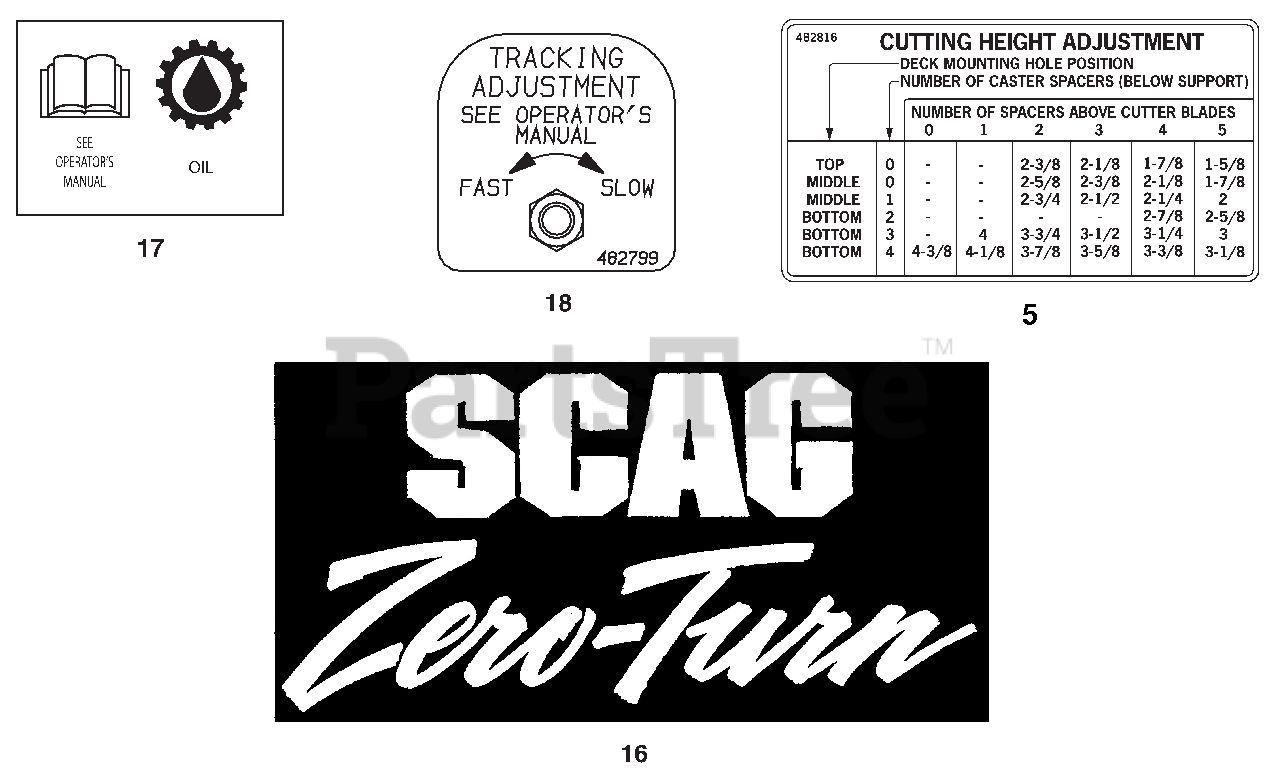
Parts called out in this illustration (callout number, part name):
5	Decal, Height of Cut
6	Decal, Metalcraft - USA
16	Decal, Scag Zero Turn
17	Decal, Oil
18	Decal, Tracking Adjustment
